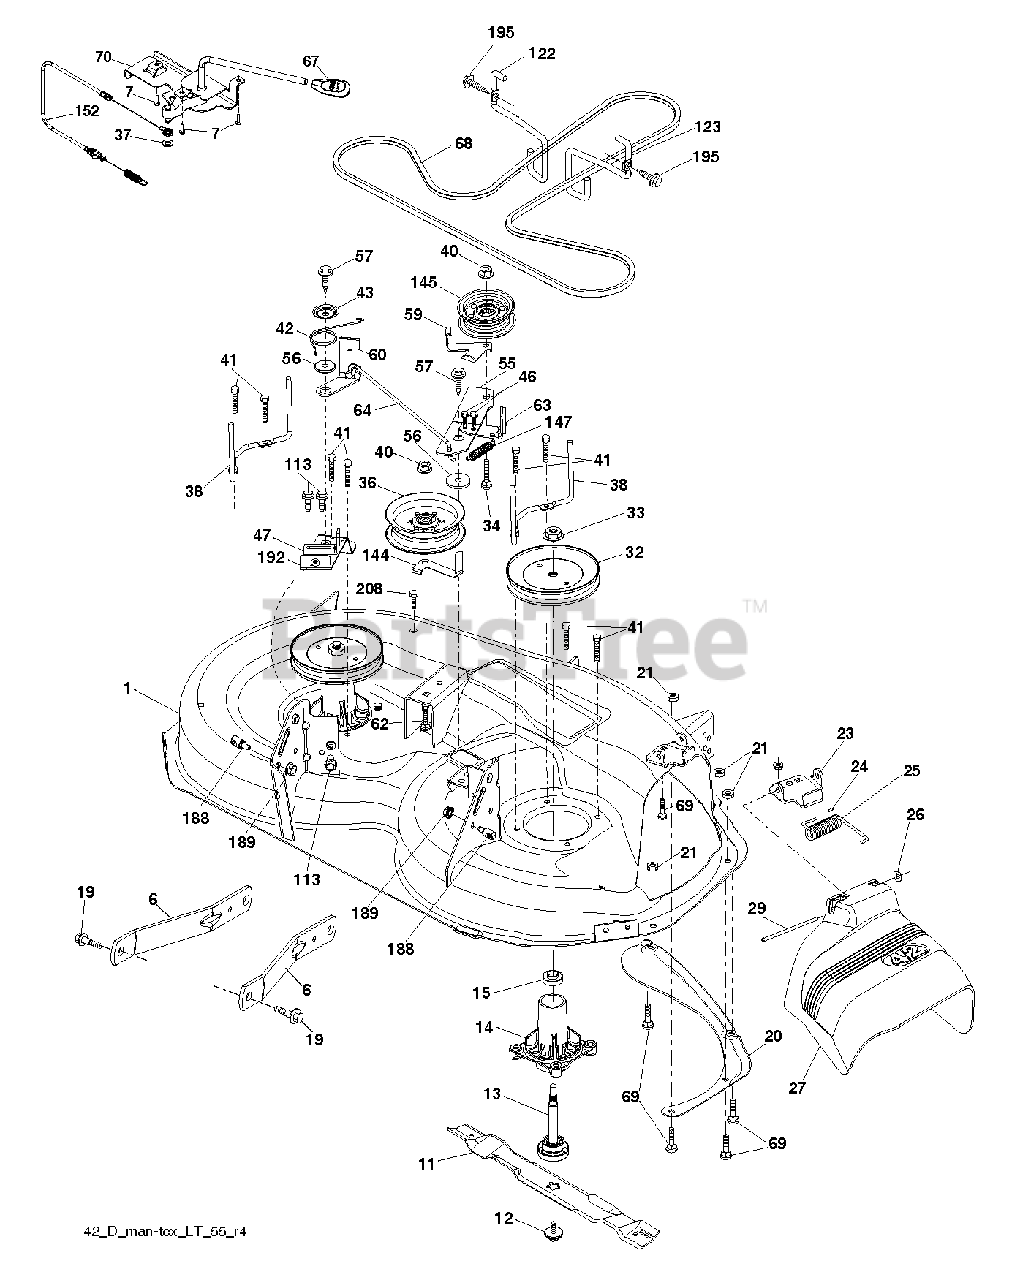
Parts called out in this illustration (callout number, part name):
6	ARM.SUSPENSION.MOWER.R
7	SCREW.#10 X 0.750.BOS (2 2)
11	42" HI-LIFT BLADE
12	Screw, 7/16 X 20 X 1"
13	Mandrel Assembly, Non-Greaseable
14	HOUSING.MANDREL.4PT.
15	Extended Mandrel Bearing, Top
19	BOLT.SHOULDER
20	BAFFLE.VORTEX
21	LOCKNUT
23	BRKT.DEFLECTOR.38"2005+
24	CAP-SLEEVE LT
25	SPRING.TORSION.DEFLECT
26	NUT PUSH M
27	SHIELD.DEFLECTOR.MOWER.42"BLAC
29	ROD.HINGE
32	PULLEY.MANDREL.5.438.PD
33	NUT.FLANGE.LOCK.TOP
34	BOLT.3/8-16X1.50
36	PULLEY.IDLER.2006
38	KEEPER.BELT.MANDREL.PULLEY
40	NUT LOCK FLG 3/8-16 UNC
41	Hex Washer Head Bolt, .313-18 X 1.19
42	SPRING.TORSION.BRAKE
43	SRPING.TORSION.RETAINE
46	SCREW.1/4-20X5/8
47	BRKT.CLUTCH.CABLE
55	IDLER.ARM.42"
56	SPACER.RETAINER
57	SCREW 3/8-16X1
59	GUARD, BELT
60	ARM BRAKE MOWER
62	BOLT
64	LINK BRAKE
67	HANDLE.CLUTCH.CABLE.LT
68	BELT.DECK.DRIVE.42"
69	BOLT
70	CLUTCH.ASM.MANUAL.LT.TEX
113	BOLT.5/16HEX.WHS.HD
122	KEEPER BELT ENGINE LH
123	KEEPER BELT RH
144	KEEPER.BELT.MOWER
145	PULLEY.IDLER.48"PRIMARY
147	RETURN SPRING
152	CABLE.MECHANICAL.CLUTCH
188	STUD.FASTNER.W/ANTI-ROTATE
189	NUT LOCK HEX FLANGE 5/16-18
192	BRKT.BRAKE.STAND.LH.
195	SCREW, 3/8-16X3/4
208	SCREW 3/8-16X1/2
